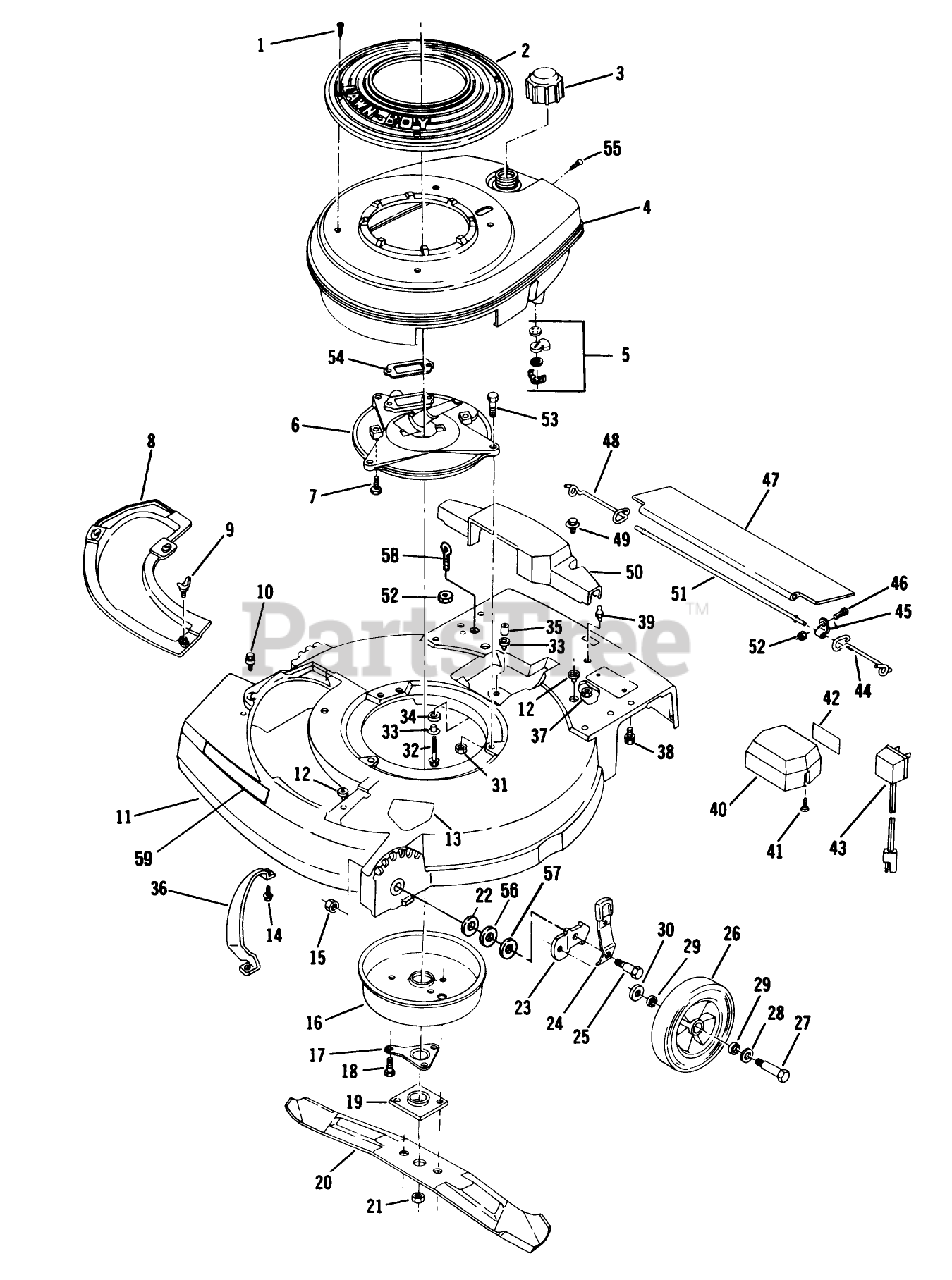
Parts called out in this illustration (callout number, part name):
1	SCREW - SELF TAPPING
3	FUEL CAP & INSERT
5	SHUT OFF VALVE KIT
7	SCREW V
9	WING SCREW LAWRE
15	LOCKNUT
16	MUFFLER COVER F
17	SUPPORT F
18	SCREW
19	PLATE AND COLLAR ASM
21	NUT-BLADE
22	WASHER
24	SPRING ARM ASM
25	BOLT
26	WHEEL & TIRE KIT
27	BOLT WHEEL
28	SPACER
29	WASHER
30	WASHER WROUGHT
31	NUT-LOCK F
33	SPACER ECK PRES
34	GROMMET
35	SPACER
36	BAR-TOE
38	SCREW
44	SPRIG T/SHLD ASOC
45	CLAMP ROD KMC
47	SHIELD
48	SPRING;TRAILING SHIELD RH
49	SCREW SEMS TRM HEX HD
51	ROD 21" ADVANCE
52	LOCKNUT E
53	SCREW-HH
55	SCREW S
56	WASHER
57	WASHER
58	BOLT-EYE
